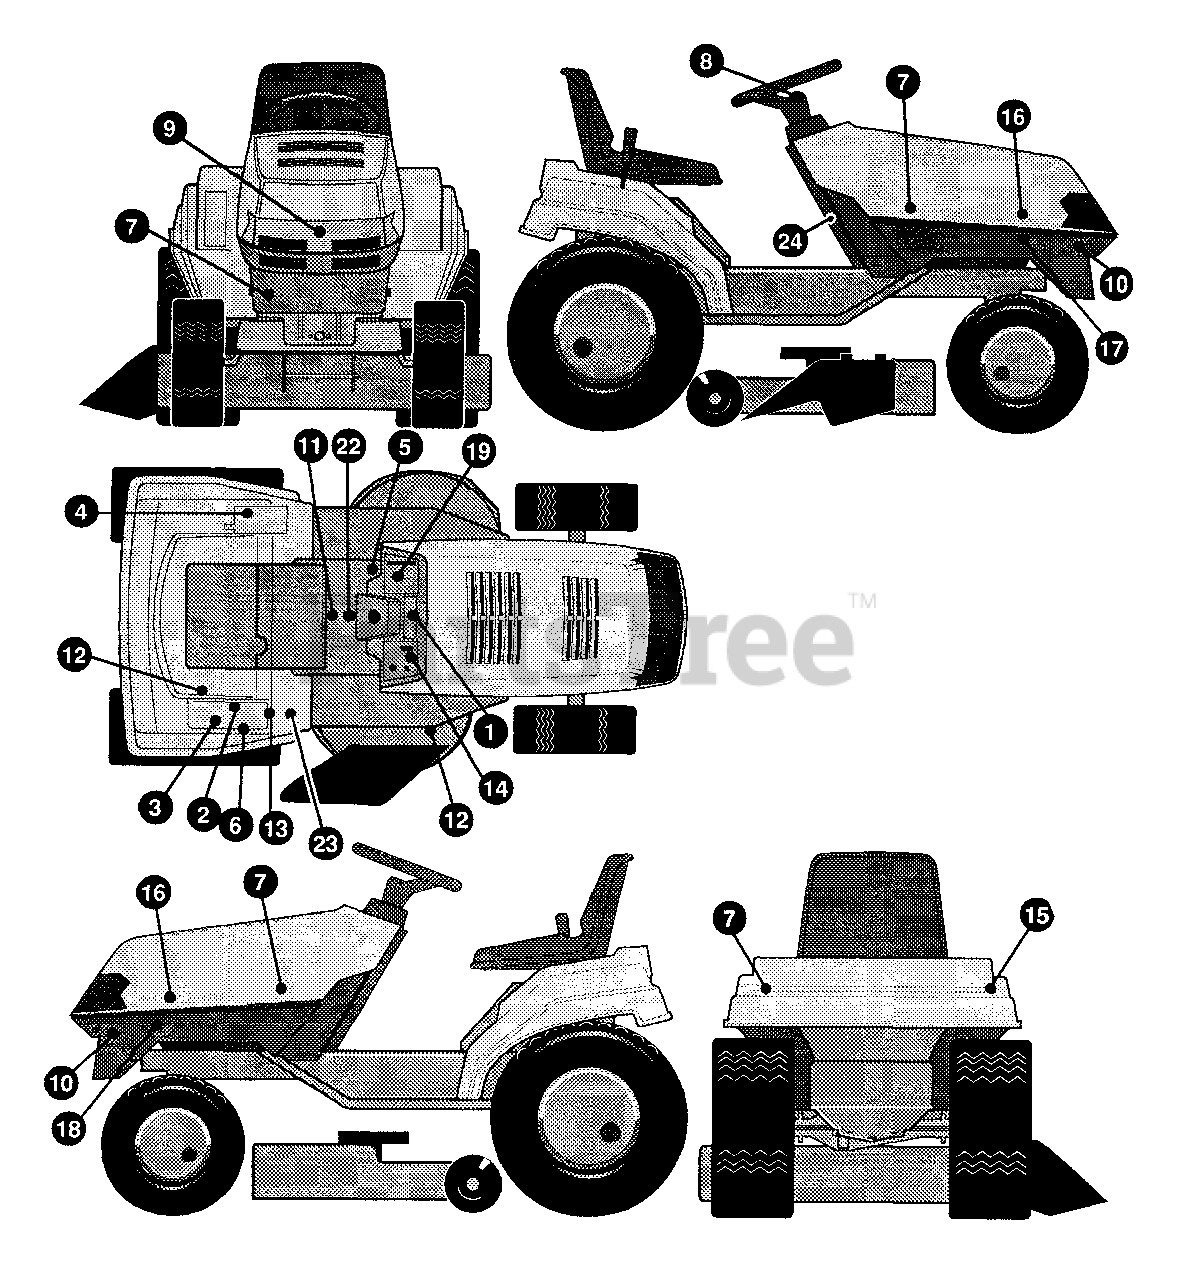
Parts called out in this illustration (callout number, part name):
1	DECAL, DASH CHG,BLK,FUEL,ALL SY
2	DECAL, BLADE CLUT/DECK HGTH ERO
3	DECAL, INSTR FRENCH (CAN) ERO LT
4	DECAL, SPEED HYDRO SIGNATURE
5	DECAL, FENDER REAR,HOOD HUSQ.
6	DECAL, GUNSIGHT CENT. STEER
7	DECAL, GUNSIGHT CLEAR BACK
8	DECAL, WHEEL 4 STEER HUSQ.
9	DECAL, INSTRUC CONSOLE TOP
10	DECAL, 4WS PATENT NO. 5048853
11	DECAL, DEPRESS CL/BRAKE
12	DECAL, DASH RH ISO HR,LG,SW
13	DECAL, MODEL #4125H
14	DECAL, HYDROSTATIC
15	DECAL, PIN STRIPE RH
16	DECAL, PIN STRIPE LH
17	DECAL, RELIEF VALVE
18	DECAL, DASH LEFT ENGLISH/ISO
21	DECAL, OPER INSTR ERO TOP FRAME
22	DECAL, DANGER FRENCH,ENGLISH
23	DECAL, PARK BRKE EXPORT
